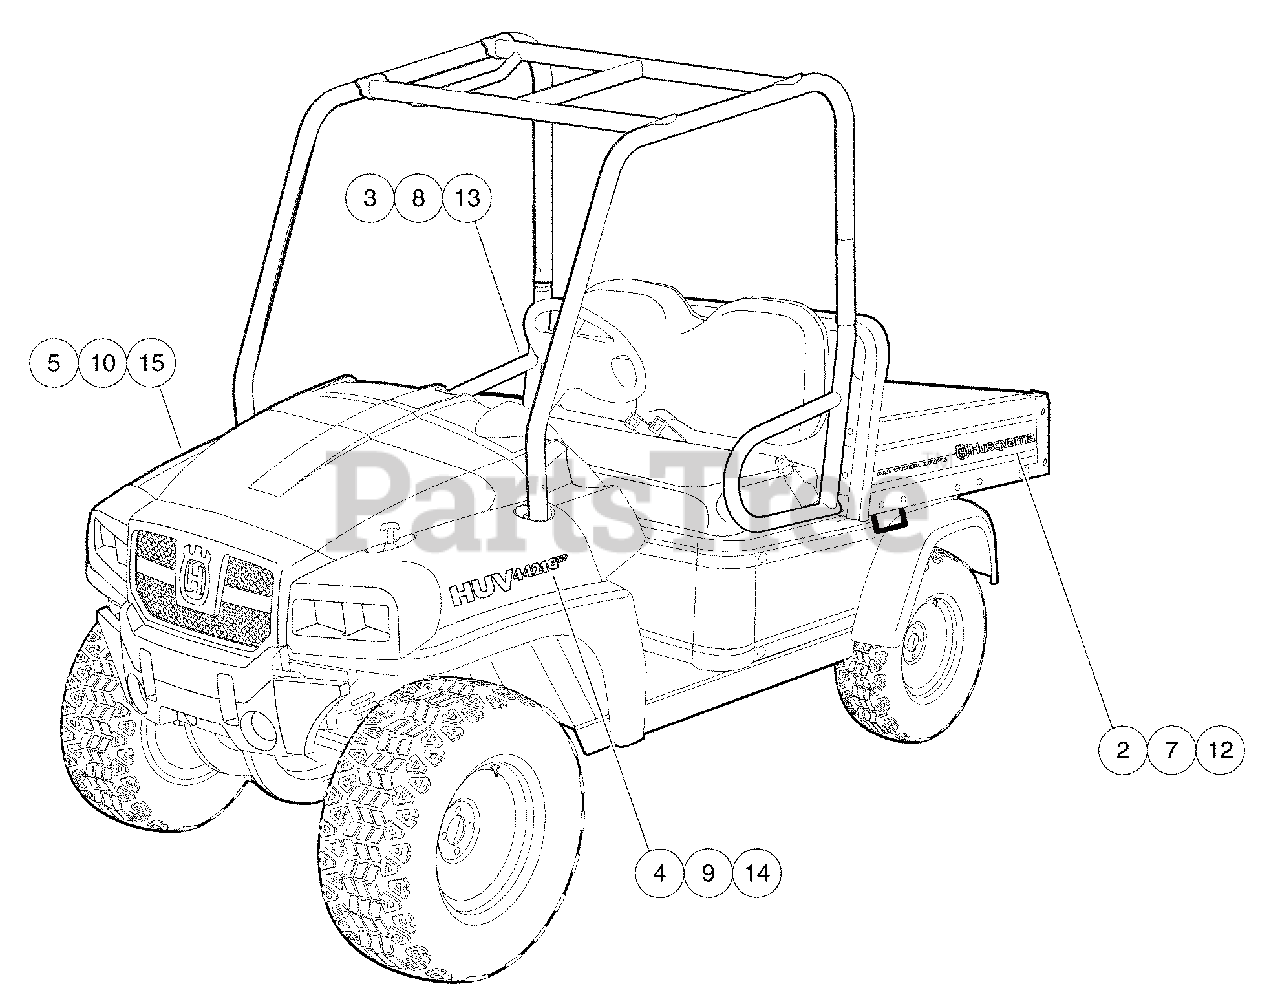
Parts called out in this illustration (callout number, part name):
1	Instl,decal,huv4421gxp,moff
2	Decal, Bed, Huv, Moff, Ds
3	Decal, Bed, Huv, Moff, Ps
4	Decal, Huv 4421gxp, Moff, Ds
5	Decal, Huv 4421gxp, Moff, Ps.
7	Decal, Bed, Huv, Orange, Ds
8	Decal, Bed, Huv, Orange, Ps
9	Decal,huv 4421gxp, Orange, Ds.
10	Decal,huv 4421gxp, Orange, Ps.
11	Instl,decal,huv4421gxp,olv Grn
12	Decal, Bed, Huv, Olv Grn, Ds
13	Decal, Bed, Huv, Olv Grn, Ps
14	Decal,huv 4421gxp, Olv Grn, Ds
15	Decal,huv 4421gxp, Olv Grn, Ps.
